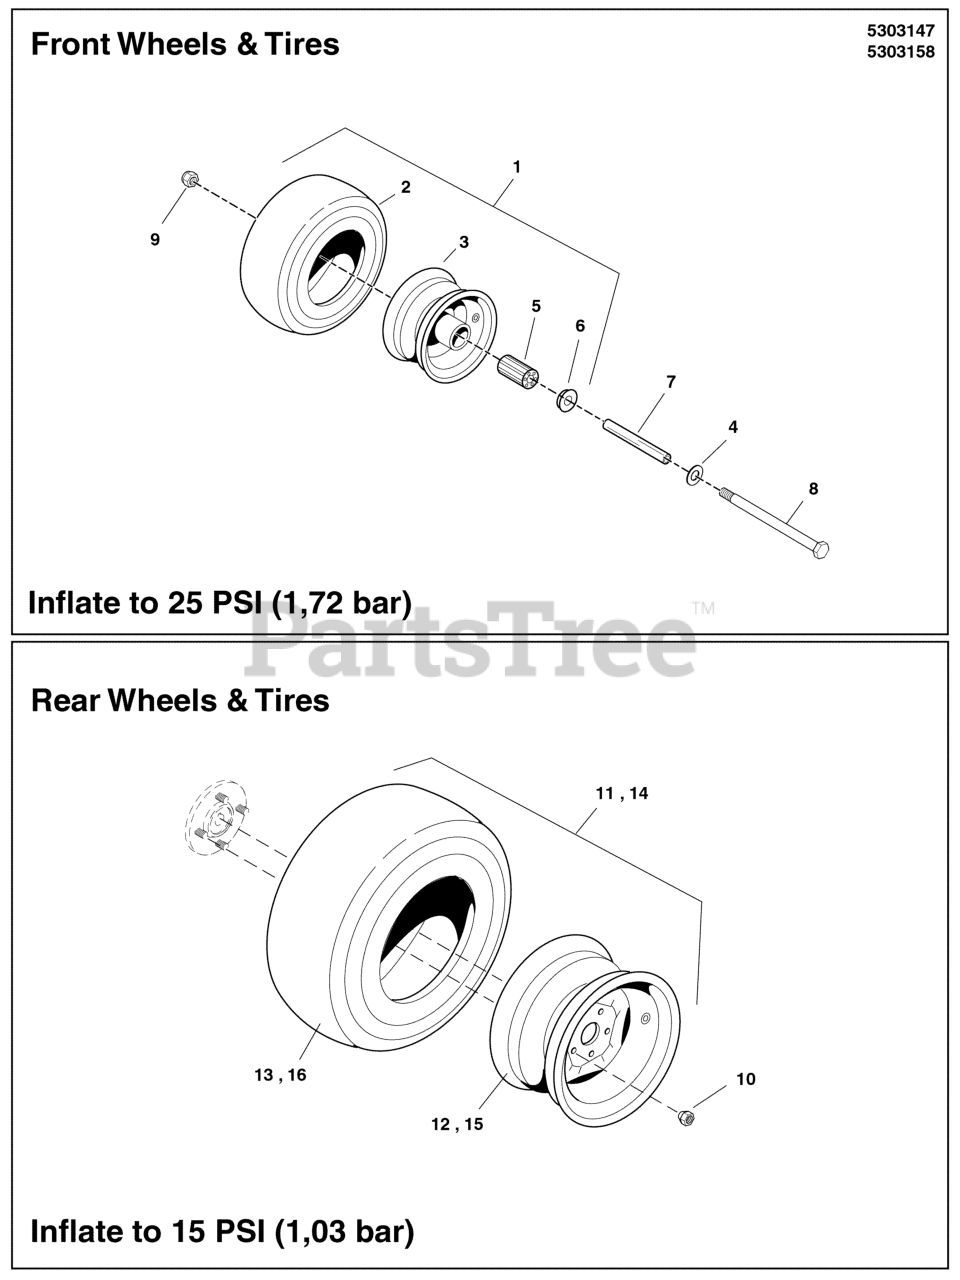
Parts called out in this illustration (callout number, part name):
1	WHEEL, CASTER, 11 X 4.0-5 SILVER BEAD LO
2	TIRE, FRONT, 11X4.0-5
3	WHEEL FOR 11X4.0-5 TIRE ASSM
4	WASHER, 1/2 SAE
5	BEARING, CASTER WHEEL, 11 X 4.0-5
6	BEARING, RETAINER
7	CASTER AXLE DDSH
8	BOLT, 1/2-13 X 7 GD5 YZ
9	NUT, Hex Flange, Nylock, 1/2-13
10	NUT, 1/2-20, FOR WHEEL BOLT SILVER
11	TIRE/WHEEL ASM, 22X11-10, TURF MASTER
12	WHEEL, 10 X 7 4/4, 0" OFFSET
13	TIRE, 22 X 11.00-10, 4 PLY
14	TIRE ASM, 20X8.00-10, 4 BOLT
15	WHEEL, 10 X 7, 4/4 BC, 1.12" POS OFFSET
16	TIRE, 20 X 8.00-10 NHS, 4 PR TURF MASTER
